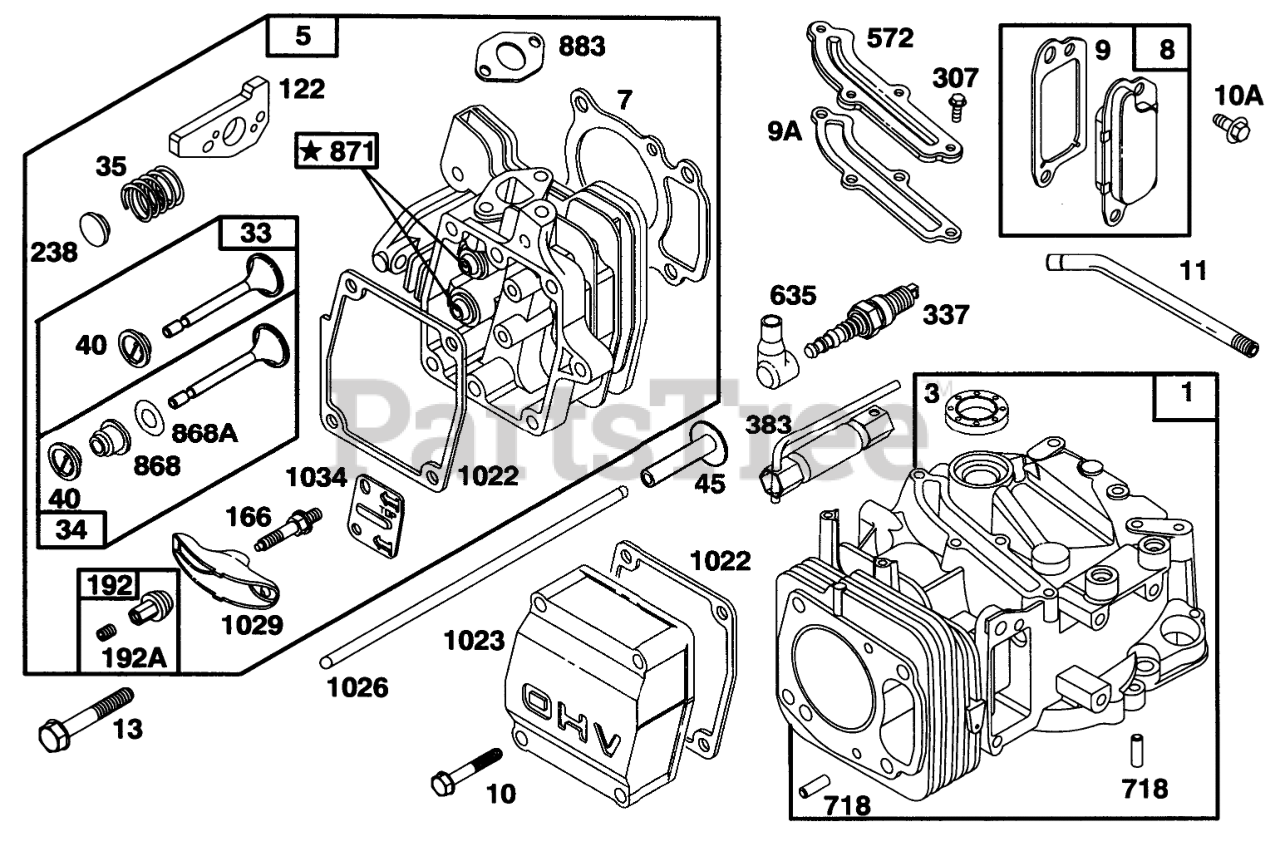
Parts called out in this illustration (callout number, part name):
1	CYLINDER ASSEMBLY
3	SEAL - OIL
5	CYLINDER HEAD
7	CYLINDER HEAD GASKET
8	Breather Assy
9	BREATHER GASKET
9A	GASKET-BREATHER
10	HEX HEAD SCREW
10A	HEX HEAD SCREW
11	TUBE - BREATHER
13	SCREW - CYLINDER HEAD
33	EXHAUST VALVE
34	INTAKE VALVE
35	VALVE SPRING
40	SPRING RETAINER
45	VALVE TAPPET
122	ADAPTER ASSEMBLY
166	ROCKER ARM STUD
192	NUT - HEX SPECIAL
192A	SCREW SET
238	VALVE CAP
307	SCREW - SEM
337	PLUG-SPARK
383	WRENCH-SPARK PLUG
572	BAFFLE - CYCLINDER
635	SPARK PLUG ELBOW
718	DOWEL - SLEEVE
868	ASM - VALVE SEAL
868A	Seal-Valve
871	Bushing-Guide
883	EXHAUST GASKET
1022	ROCKER COVER GASKET
1023	COVER - VALVE
1026	PUSH ROD
1029	ROCKER ARM
1034	PUSH ROD GUIDE
